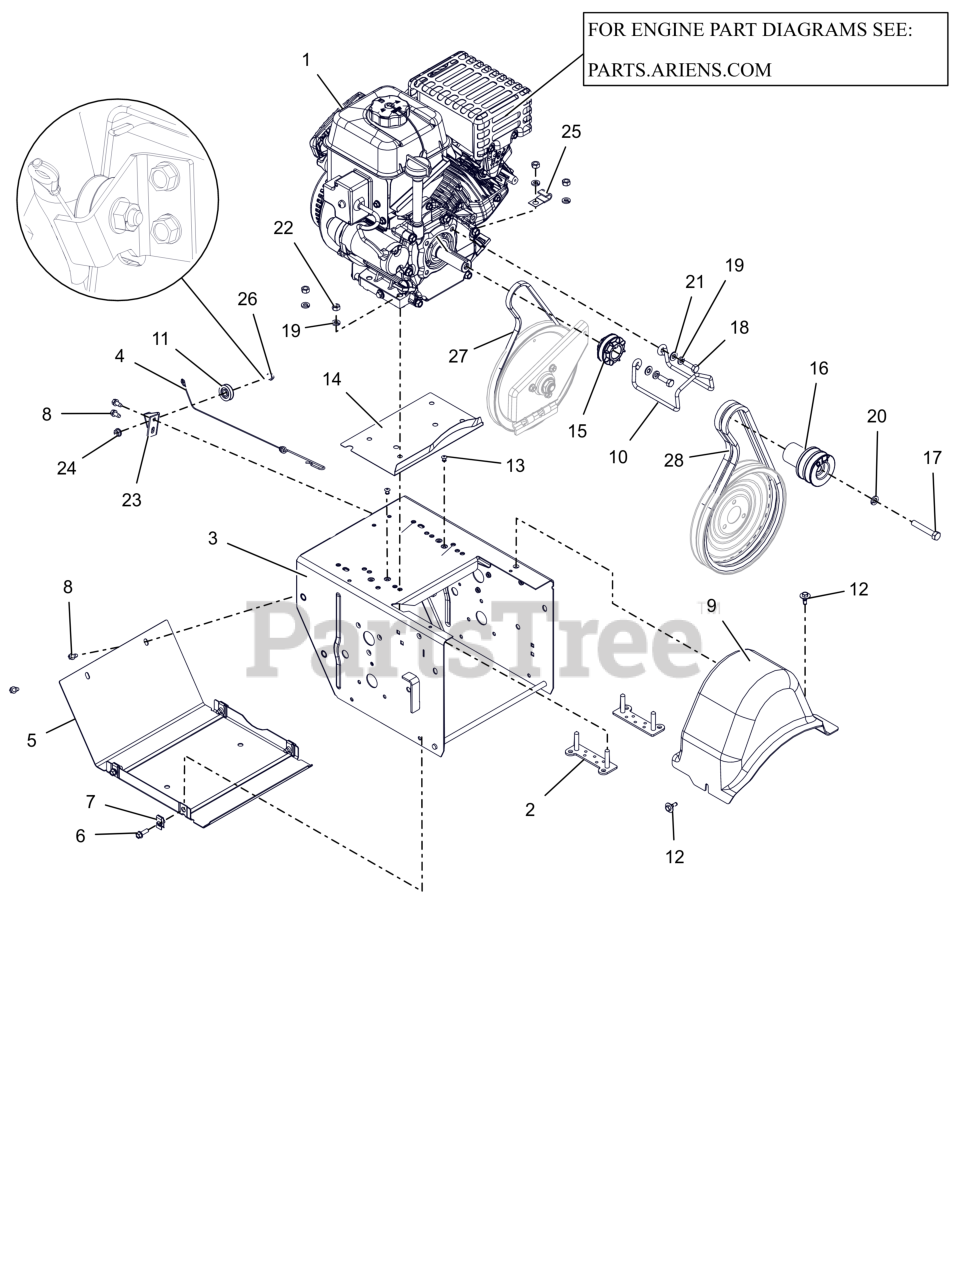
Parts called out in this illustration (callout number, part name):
1	Engine, AX 254 OPP 120V/60W
2	STRAP, BOLT - SMALL ENGINE
3	FRAME, MAIN - 14GA DELUXE (ORANGE)
4	CABLE, LOWER TRACTION,SS & PRO
5	COVER, BOTTOM
6	BLT, HWH .25-20X.75 G5 ZCC
7	NUT-RTNR .25-20X.56
8	SCR-TAP .25-20X.50 HWH ZCC
9	COVER, BELT-SMALL
10	FINGER, BELT
11	PULLEY, CABLE
12	SCR-TAP .25-20X.5 CAPTIVE
12	NUT-PUSH .25X.50 O.D.
12	SCR, TAP .25-20X.50 LG HWH ZCC
13	RVT, POP .1875 ZCC
14	BAFFLE, WATER-SMALL
15	SHEAVE, DRIVE
16	SHEAVE, ATTACHMENT - STANDARD 2 GRV
17	BLT, HEX .38-24X2.25 G5 ZCC
18	BLT, HEX 0.3125-24X1 G5 ZCC
19	WSHR, LK-HVY .312X.097 ZCC
20	WSHR,LK-REG .375X.094 ZCC
21	WSHR,FLT .344X.688X.065 ZCC
22	NUT, HEX .312-18 ZCC
23	BRACKET, CABLE PULLEY
24	NUT-LK-TOP-FLG .250-20 GF ZCC
25	J-CLAMP
26	BOLT, SHLDR -.375 X .375 X .25-20
27	V-BELT, 3L-WRAPPED
28	V-BELT, HA-RAW EDGE (SET)
